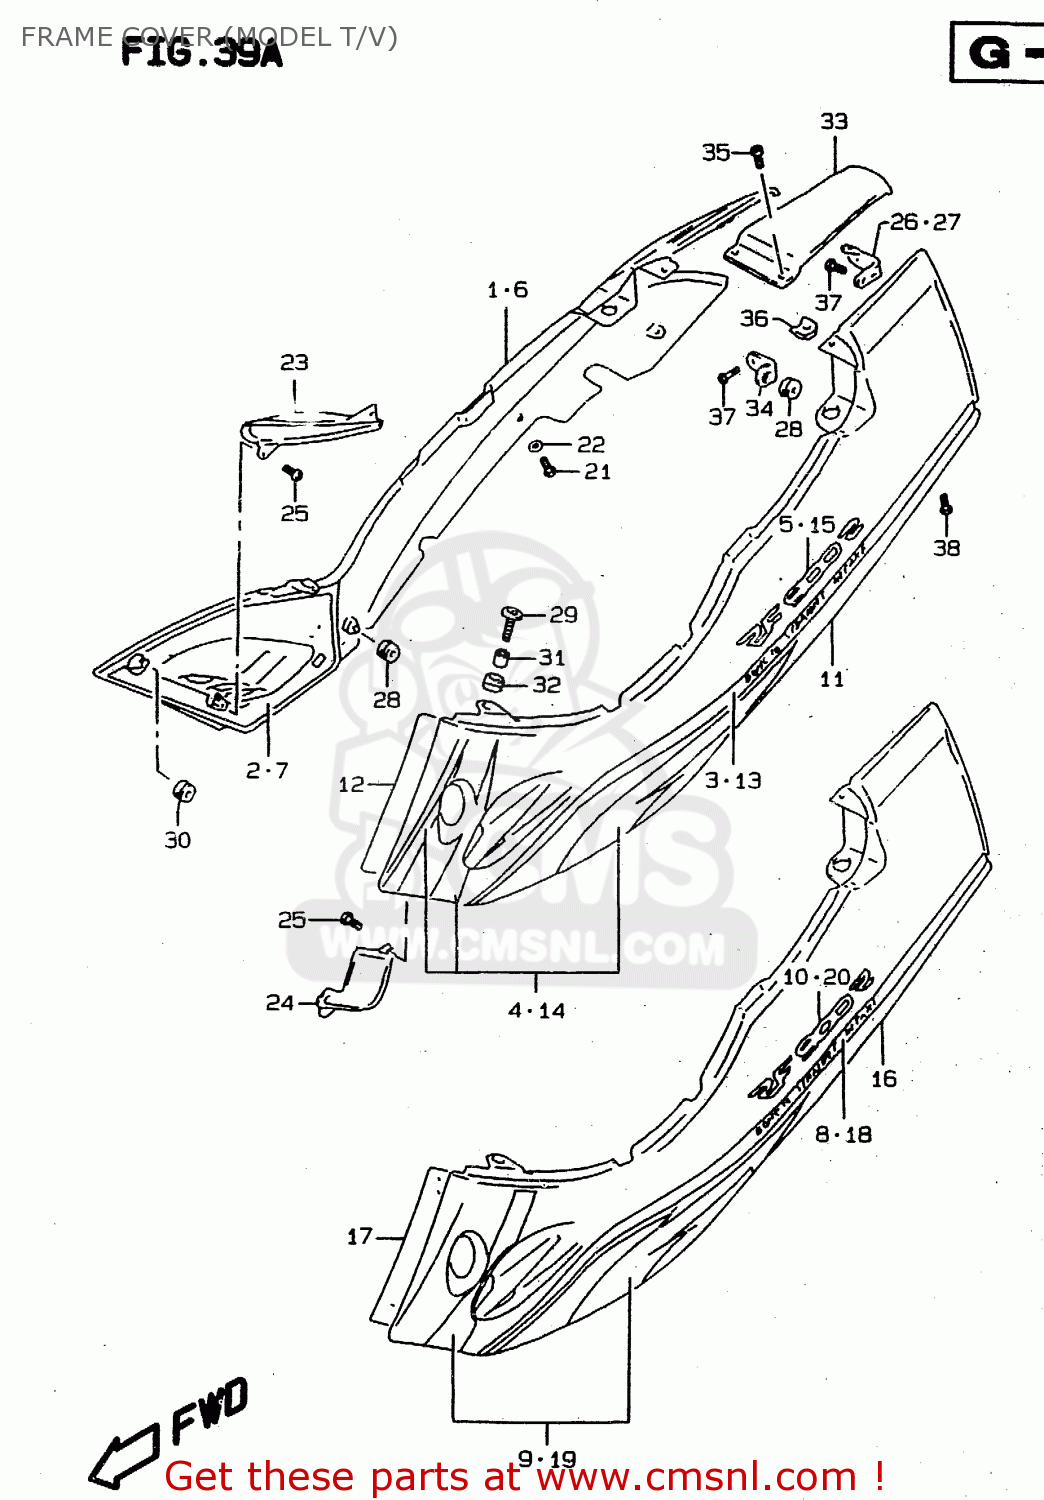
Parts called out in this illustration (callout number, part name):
1	COVER ASSY,FRAME,R(GRAY)
2	SHIELD,FRAME COVER HEAT
3	TAPE SET,FRAME COVER S
4	TAPE SET,FRAME COVER,R
5	EMBLEM,FRAME COVER
6	COVER ASSY,FRAME,R(BLACK)
7	SHIELD,FRAME COVER HEAT
8	TAPE SET,FRAME COVER S
9	TAPE SET,FRAME COVER,R
10	EMBLEM,FRAME COVER
11	COVER,FRAME,LEFT (GRAY)
12	SHIELD,FRAME COVER HEAT,L
13	TAPE SET,FRAME COVER S
14	TAPE SET,FRAME COVER,L
15	EMBLEM,FRAME COVER
16	COVER ASSY,FRAME,L(BLACK)
17	SHIELD,FRAME COVER HEAT,L
18	TAPE SET,FRAME COVER STRIPE,L
19	TAPE SET,FRAME COVER,L
20	EMBLEM,FRAME COVER
21	SCREW 5X12
22	WASHER(5.2X14X1.5)
23	COVER,INNER,RIGHT
24	COVER,INNER,L
25	SCREW
26	BRACKET,FRAME COVER,R
27	BRACKET,FRAME COVER,L
28	CUSHION
29	BOLT(6X25)
30	CUSHION,FRAME COVER FR
31	SPACER(6.5X9X11)
32	CUSHION
33	COVER,FRAME CTR
34	BRACKET,RR COMBINATION LAMP
35	SCREW 5X12
36	NUT
37	SCREW
38	SCREW
